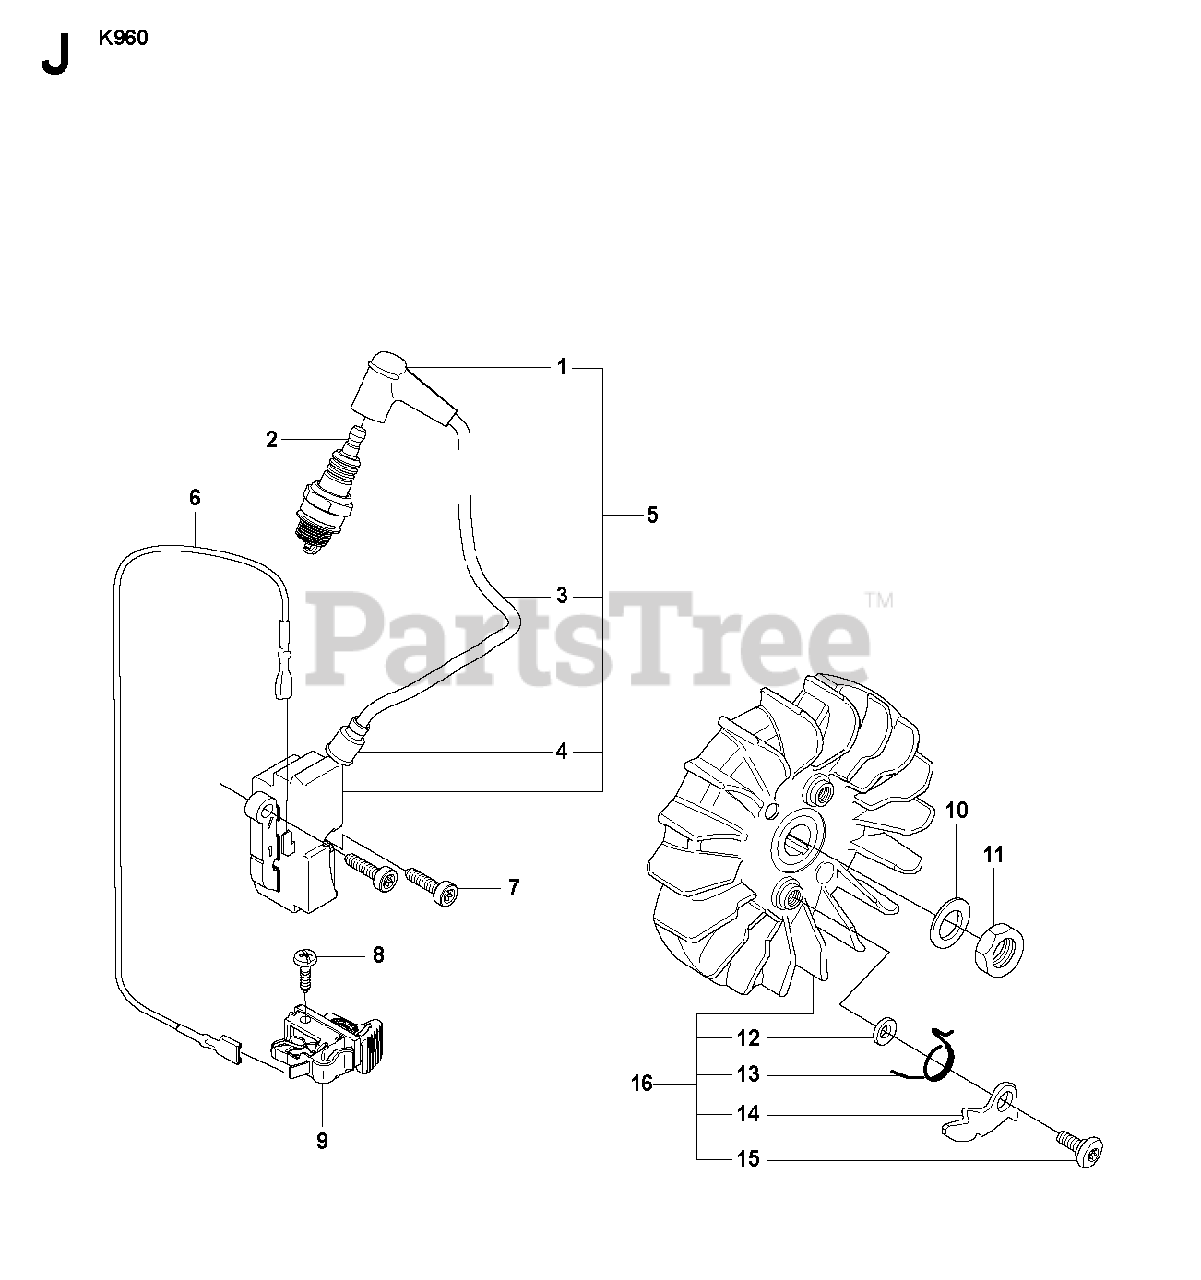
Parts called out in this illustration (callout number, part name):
1	SPARK PLUG CAP
3	IGNITION CABLE
5	IGNITION MODULEIncl. 1, 3, 4
7	SCREW ITXSCM
8	SCREW CCRPANT
9	STOP SWITCH
15	SCREW
16	FLYWHEELIncl. 12 - 15
